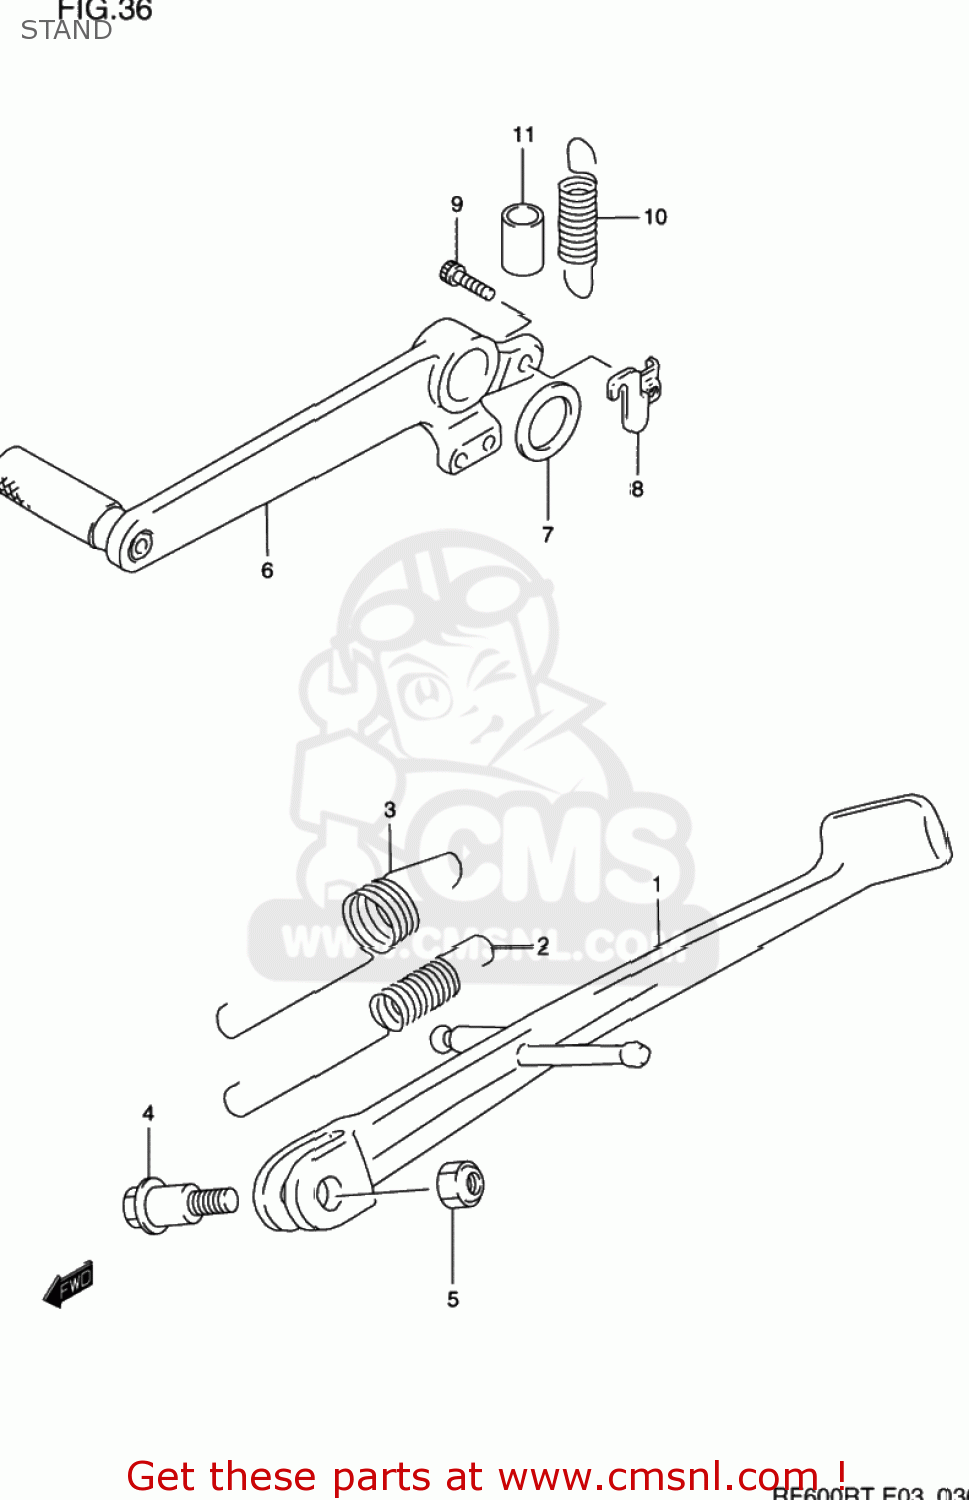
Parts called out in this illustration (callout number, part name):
1	STAND,PROP
2	SPRING
3	SPRING
4	BOLT(10X34)
5	NUT
6	PEDAL,BRAKE
7	WASHER(18X24X1)
8	BRACKET,STOP LAMP SWITCH SPR
9	BOLT
10	SPRING
11	TUBE,BRAKE SPRING GUIDE
